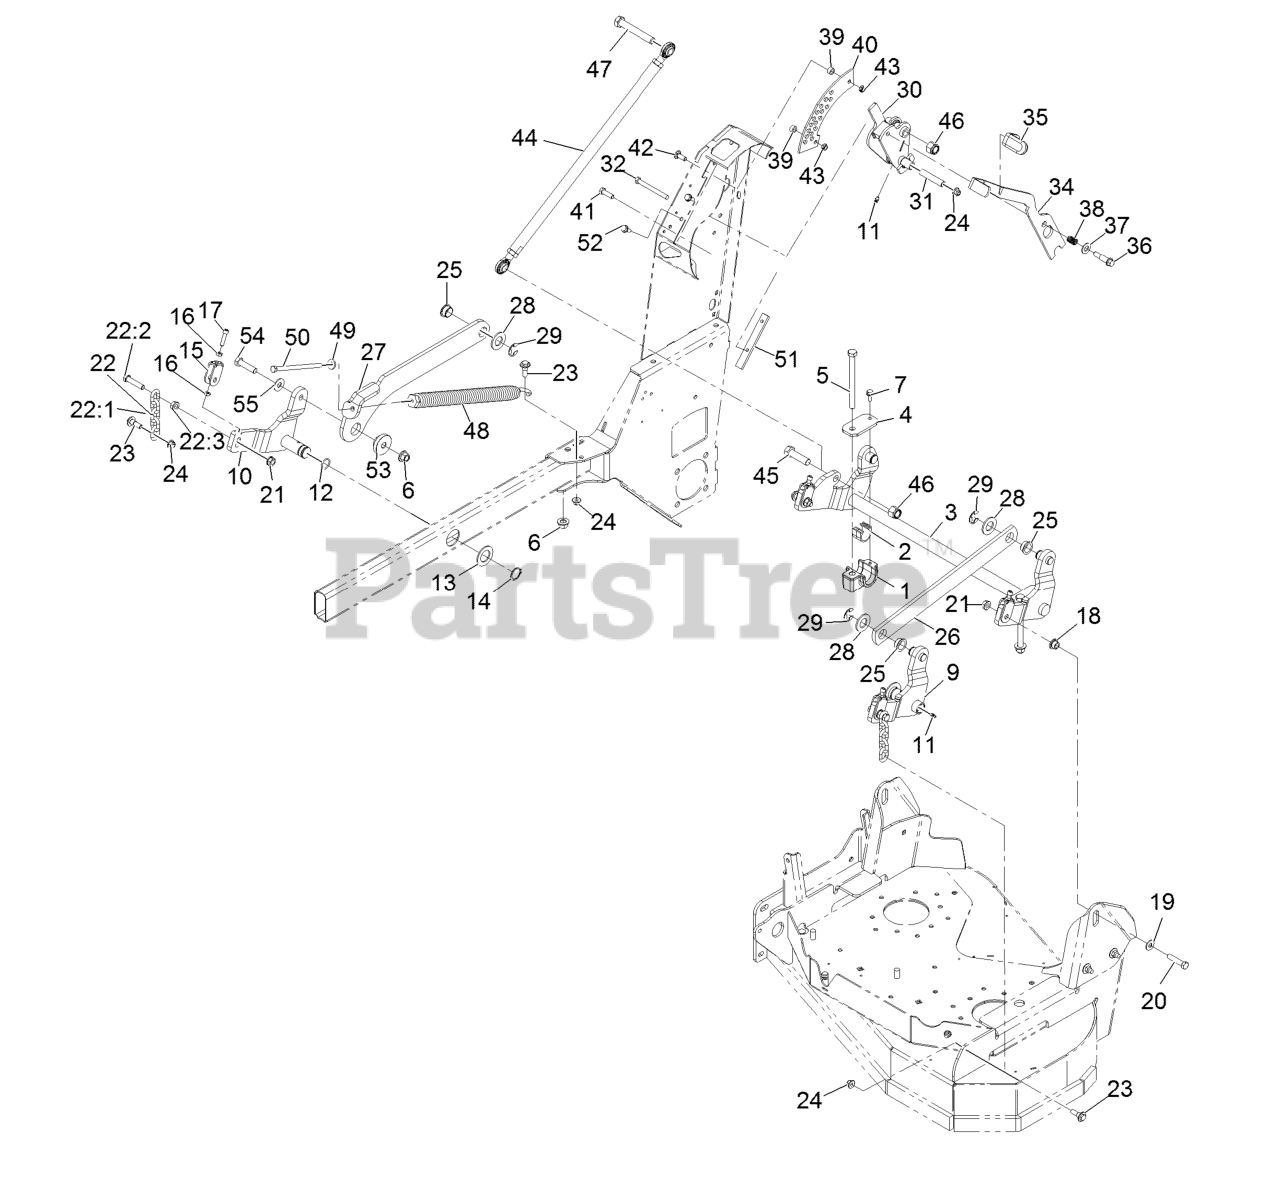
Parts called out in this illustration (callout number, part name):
1	Support-Bearing
2	Bearing-Cross Shaft, Front
3	Rear Crossshaft ASM
4	Cover-Bearing Support
5	Screw-HH 1/2-13 X 6
6	Nut-Lock 1/2-13
7	Screw-Flange
9	Decklift Arm ASM-LH
10	Decklift Arm ASM-RH
11	Zerk 1/4-28 Str Thrd Forming
12	O Ring
14	Ring-Retaining
15	Yoke-Adjust, Deck
16	Nut-Jam 5/16-18
17	Screw-Sh 5/16-18 X 1 1/4
18	Bushing-Flanged
19	Washer-3/8 Std
20	Screw-HH 7/16-14 X 2
21	Nut-Whizlock 7/16-14
22	Deck Lift Chain ASM
22:1	Chain-Lift, Deck
22:2	Screw-HH 7/16-14 X 2
22:3	Nut-Whizlock 7/16-14
23	Screw-Hex Flange 3/8-16 X .80
24	Nut-Nyloc 3/8-16 Flg
25	Bearing-Flange
26	Link-Decklift, LH
27	Link-Decklift, RH
28	Washer-7/8 SAE
30	ASM-HOC Handle
31	Bearing-HOC Pivot
32	Screw-HH 3/8-16 X 3 3/4
34	Lever-HOC
35	Grip-Lever
36	Screw-Shoulder
37	Washer-1/2 SAE
39	Bushing
40	Bracket-HOC
41	Screw-HH 3/8-16 X 1 1/4
42	Bolt-Carriage 3/8-16 X 1
43	Nut-Nyloc 3/8-16 Thin
44	HOC Link ASM
45	Screw-HH
46	Nut-Nyloc 5/8-11
47	Screw-HH
48	Spring-Extension
49	Washer-Spring Disc 3/8
50	Bolt-HH 3/8-16 X 6 Tap
51	Skid-Handle, Lift
52	Screw-HWH 5/16-18 X 3/4 Tf
53	Bushing-Flanged
54	Screw-HH 1/2-13 X 1 1/4
55	Washer-7/16 Std
